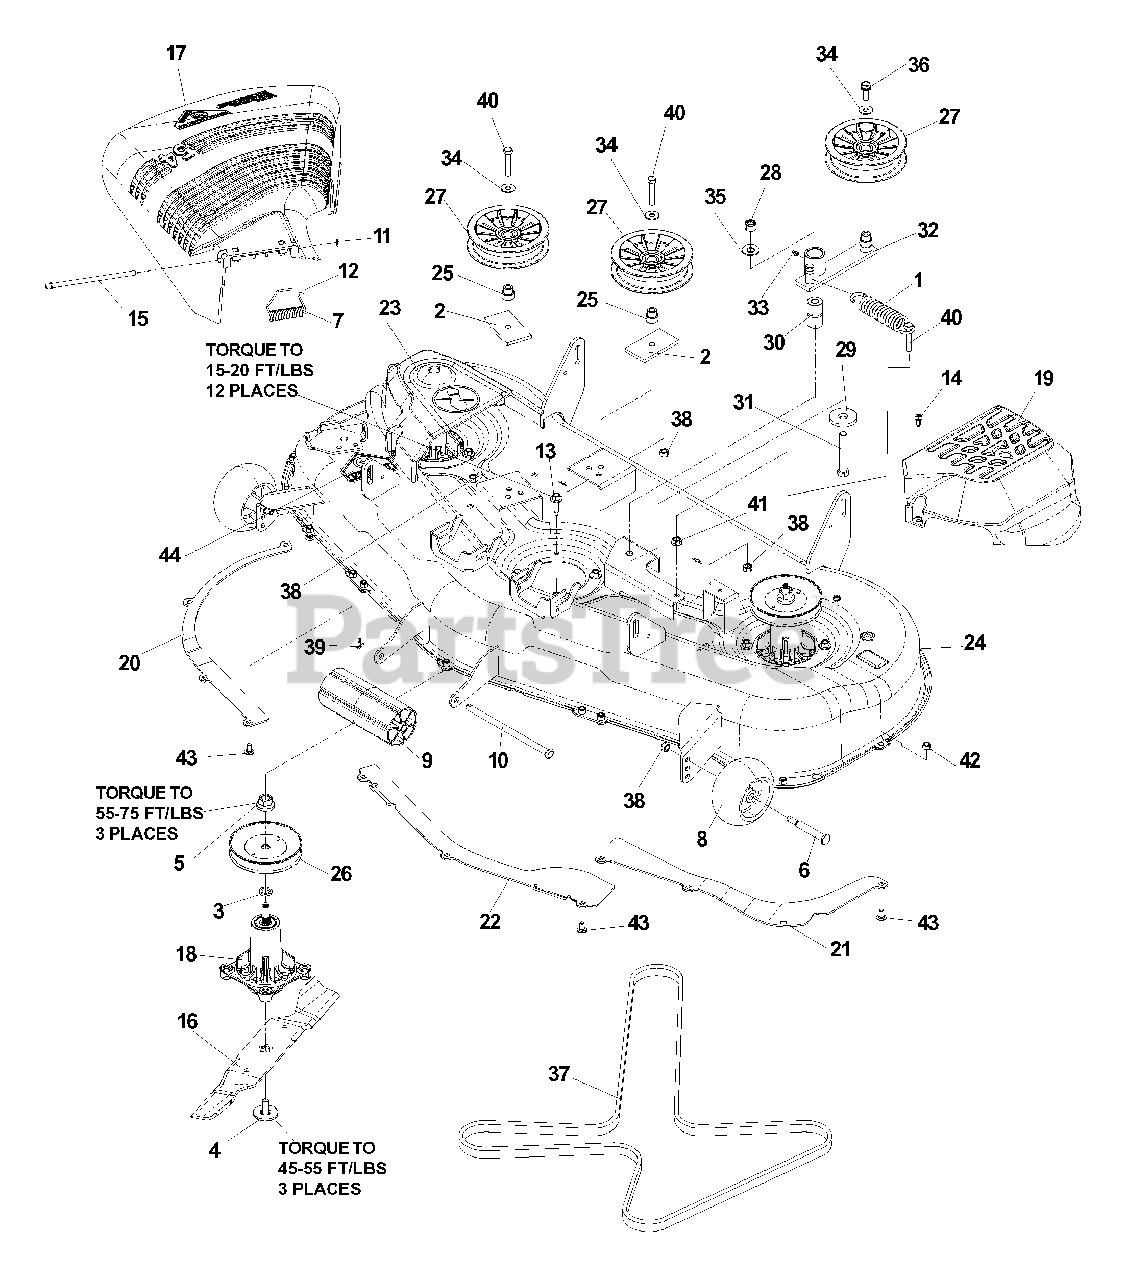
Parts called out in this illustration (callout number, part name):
1	SPRING, EXTENSION
2	PAD
3	WASHER, .675, SPACER
4	BOLT, 7/16, SPEC
5	NUT, 9/16, CENTERLOCK, GR5
6	SB, 1/2 X 2 5/8, SPEC
7	SPRING, TORSION
8	WHEEL, GAUGE
9	ROLLER, NOSE
10	ROD, ROLLER, NOSE, NARROW
11	NUT, 5/16, PUSH
12	CAP-SLEEVE
13	SCREW, 5/16-18 X 1 3/8, WASH HD, SPEC
14	SCREW, 1/4-20 X 5/8, THDROLL, SPEC
15	ROD, HINGE
16	BLADE
18	MADNREL, GREASABLE
19	BELT COVER, LEFT
20	BAFFLE, RIGHT
21	BAFFLE, LEFT
22	BAFFLE, CENTER
23	BELT COVER, RIGHT
24	DECK W/DECALS
25	IDLER BUSHING
27	IDLER PULLEY, NYLON
28	NUT, 1/2-13, NYLOC
29	WASHER, .65 X 2 X .25, SUPPORT
30	BUSHING-PIVOT
31	HCS, 1/2-13 X 3 1/4, GR5
33	ZERK, STRAIGHT, 1/4-28
34	WASHER, 3/8
35	WASHER, .562 X 1.38 X 14
36	HCS, 3/8-16 X 1, GR5, WHIZLK
38	NUT, 3/8-16, NYLOC
39	PIN COTTER, 1/8 X 3/4
40	HCS, 3/8-16 X 2, GR5
41	NUT, 3/8-16, WHIZLK
42	NUT, 5/16-18, NYLOC
43	RHSNB, 5/16-18 X 5/8, GR5
44	DECAL, WARNING
